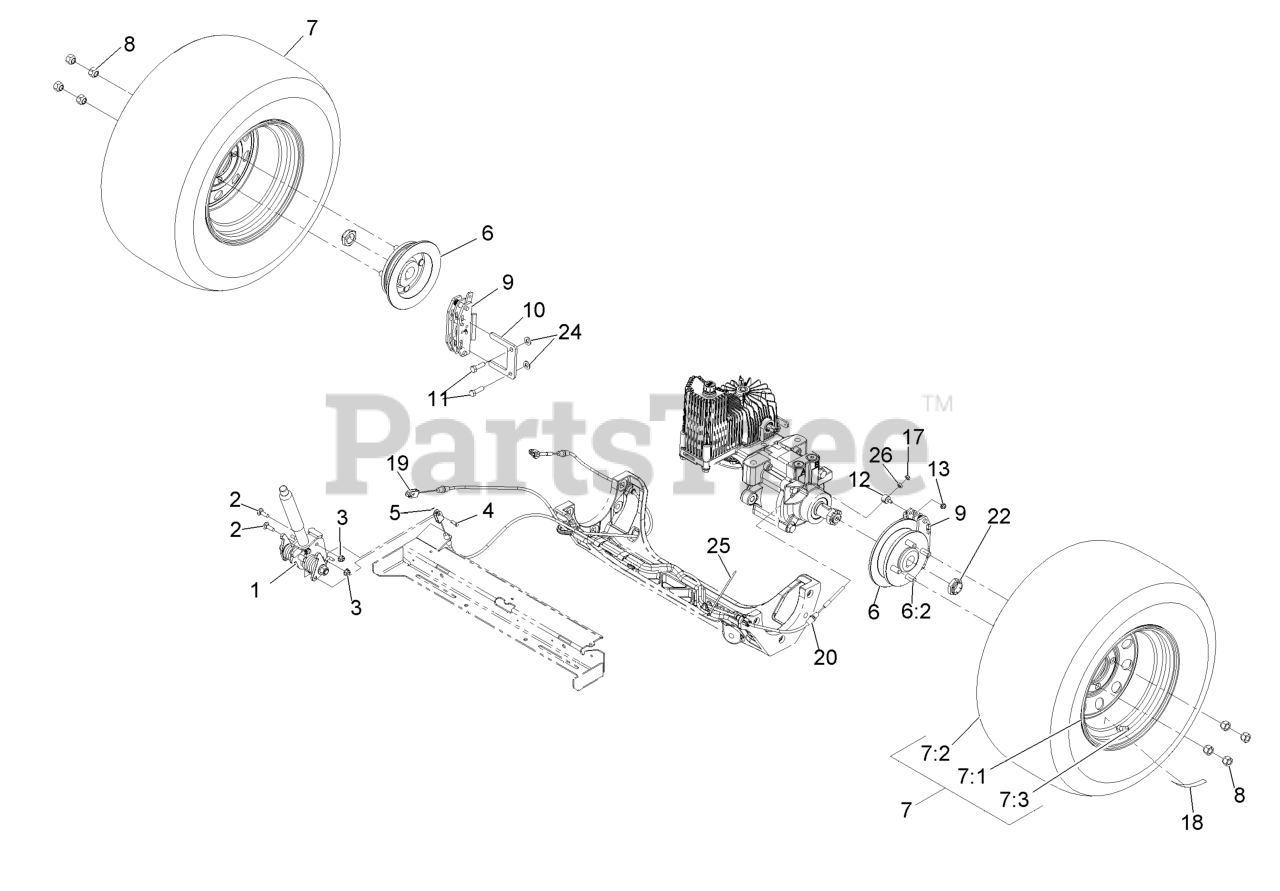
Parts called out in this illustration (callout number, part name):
1	BRAKE HANDLE ASM
2	BOLT-CARR
3	NUT-HF, NI
4	PIN-CLEVIS
5	PIN-COTTER
6	WHEEL HUB ASM
6:2	STUD-WHEEL
7	TIRE AND WHEEL ASM
7:2	TIRE-TURF MASTER
7:3	Stem-Valve
8	NUT-LUG
9	CALIPER-BRAKE
10	PLATE-MOUNT, BRAKE
11	SCREW-LOCK, PATCH
17	NUT-LOCK, NI
22	LOCKNUT
24	WASHER-FLAT
25	TIE-CABLE
26	NUT-HEX
